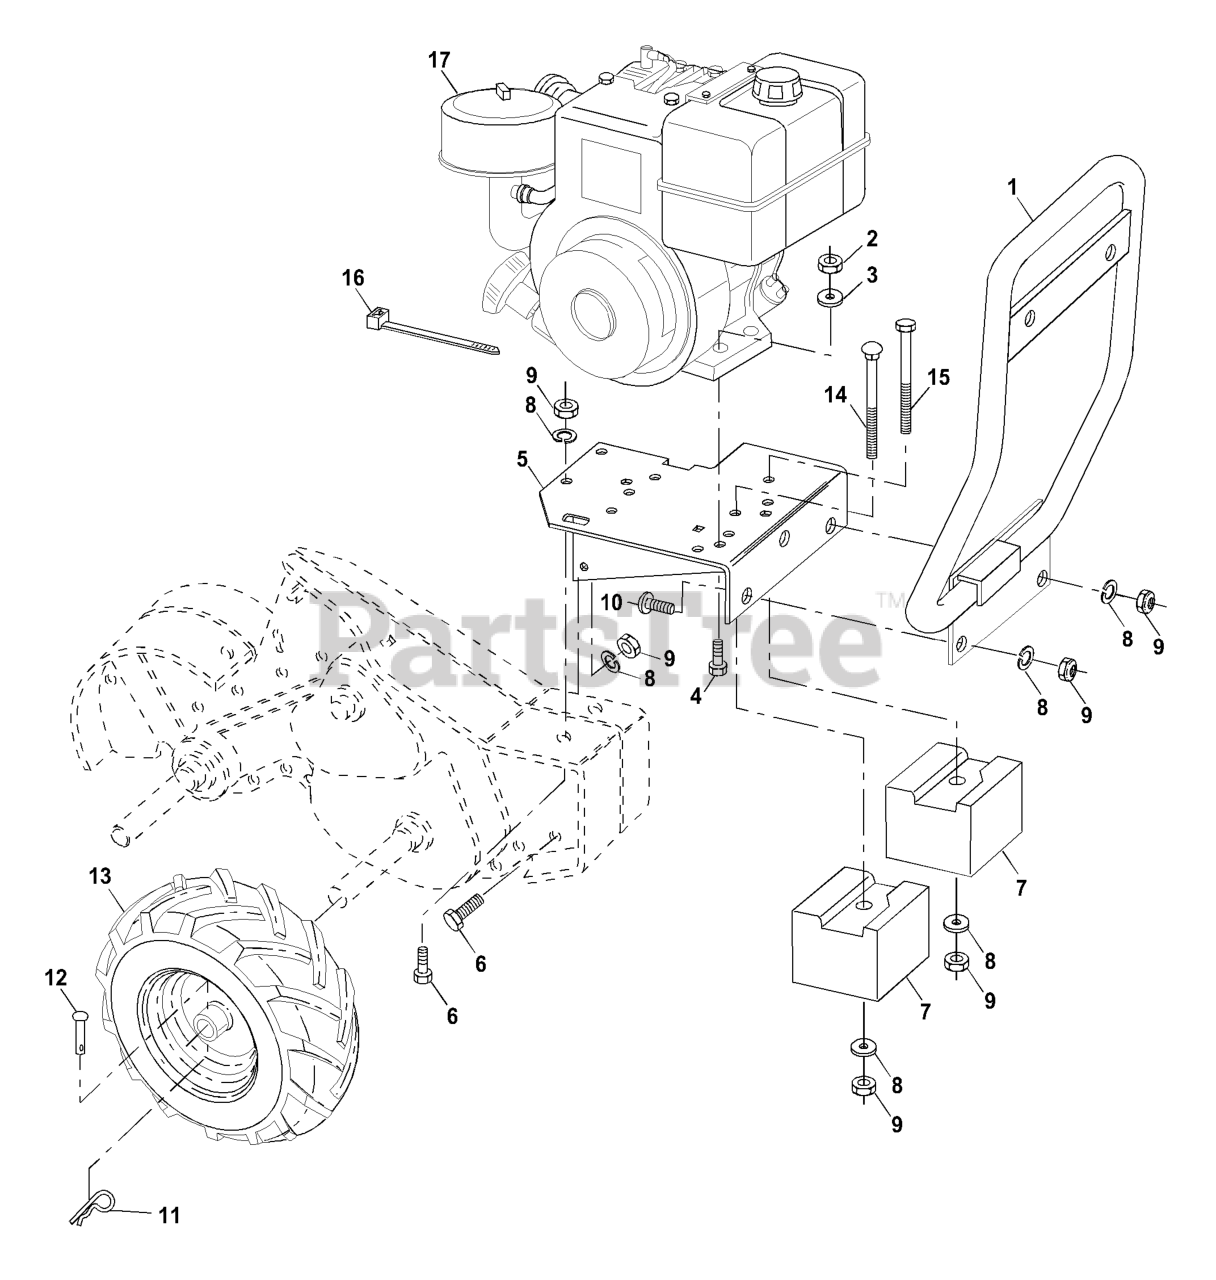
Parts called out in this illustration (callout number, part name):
2	NUT
3	WASHER.LOCK.HVY.HLCL.SPR.5/16
4	BOLT, HEX 5/16-18X1-3/4
5	ENGINE BRACKET
6	BOLT
7	COUNTER WEIGHT RH
8	WASHER, LOCK 3/8
9	NUT.HEX.3/8-16UNC
10	BOLT D
11	SPRING TI
13	TIRE.16X4-8.CHEVRON.TILLER
13	RIM.16X4X8.WHITE
13	VALVE STEM LT
14	Bolt, Carriage 3/8-16 x 4-1/2
15	BOLT, HEX 3/8-16X4-1/2
16	TIE CABLE CRT
17	Engine, Briggs & Stratton
